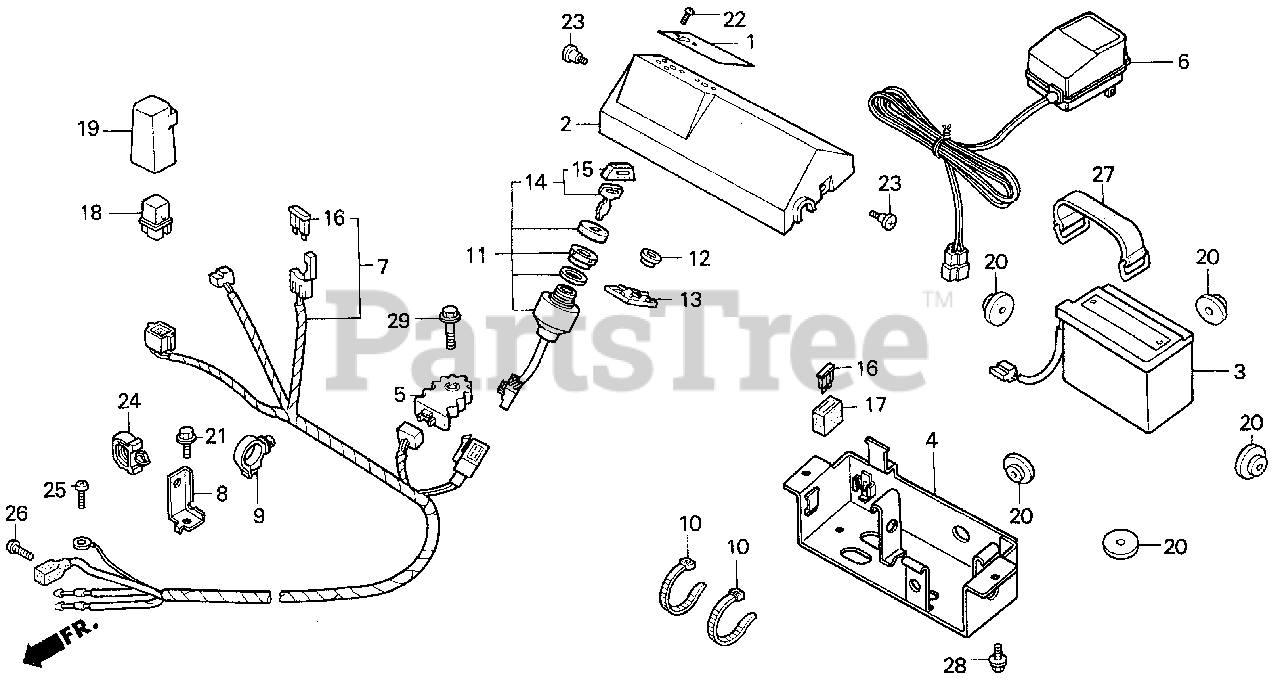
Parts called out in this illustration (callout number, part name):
1	PLATE, ENGINE SWITCH OPERATION (A,C,E)
2	PANEL, CONTROL
3	BATTERY ASSY. (LCS2912H)
3	BATTERY ASSY.
4	CASE, BATTERY
5	RECTIFIER, REGULATE
5	RECTIFIER, REGULATOR
6	CHARGER ASSY., BATTERY
7	HARNESS ASSY., MAIN
8	BRACKET, HARNESS CLIP
9	CLAMP, ENGINE SUB-WIRE
10	TIE, CABLE
11	SWITCH ASSY., COMBINATION
12	COLLAR, COMBINATION SWITCH
13	PLATE, COMBINATION SWITCH
14	KEY ASSY., COMBINATION SWITCH
16	FUSE (F1) (LITTEL)
17	SUSPENSION, TURN SIGNAL RELAY (MITSUBA)
18	RELAY, STARTER (OMRON)
19	SUSPENSION, STARTER RELAY (OMRON)
20	RUBBER, BATTERY BOX
21	BOLT, FLANGE (6X12) (CT200)
22	SCREW (3X8)
23	SCREW, SPECIAL (6X12)
24	CLIP, WIRE HARNESS (10MM)
25	SCREW, PAN (4X6)
26	SCREW, PAN (5X8)
27	BAND B2, BATTERY
28	BOLT, FLANGE (6X10)
29	BOLT, FLANGE (6X30)
